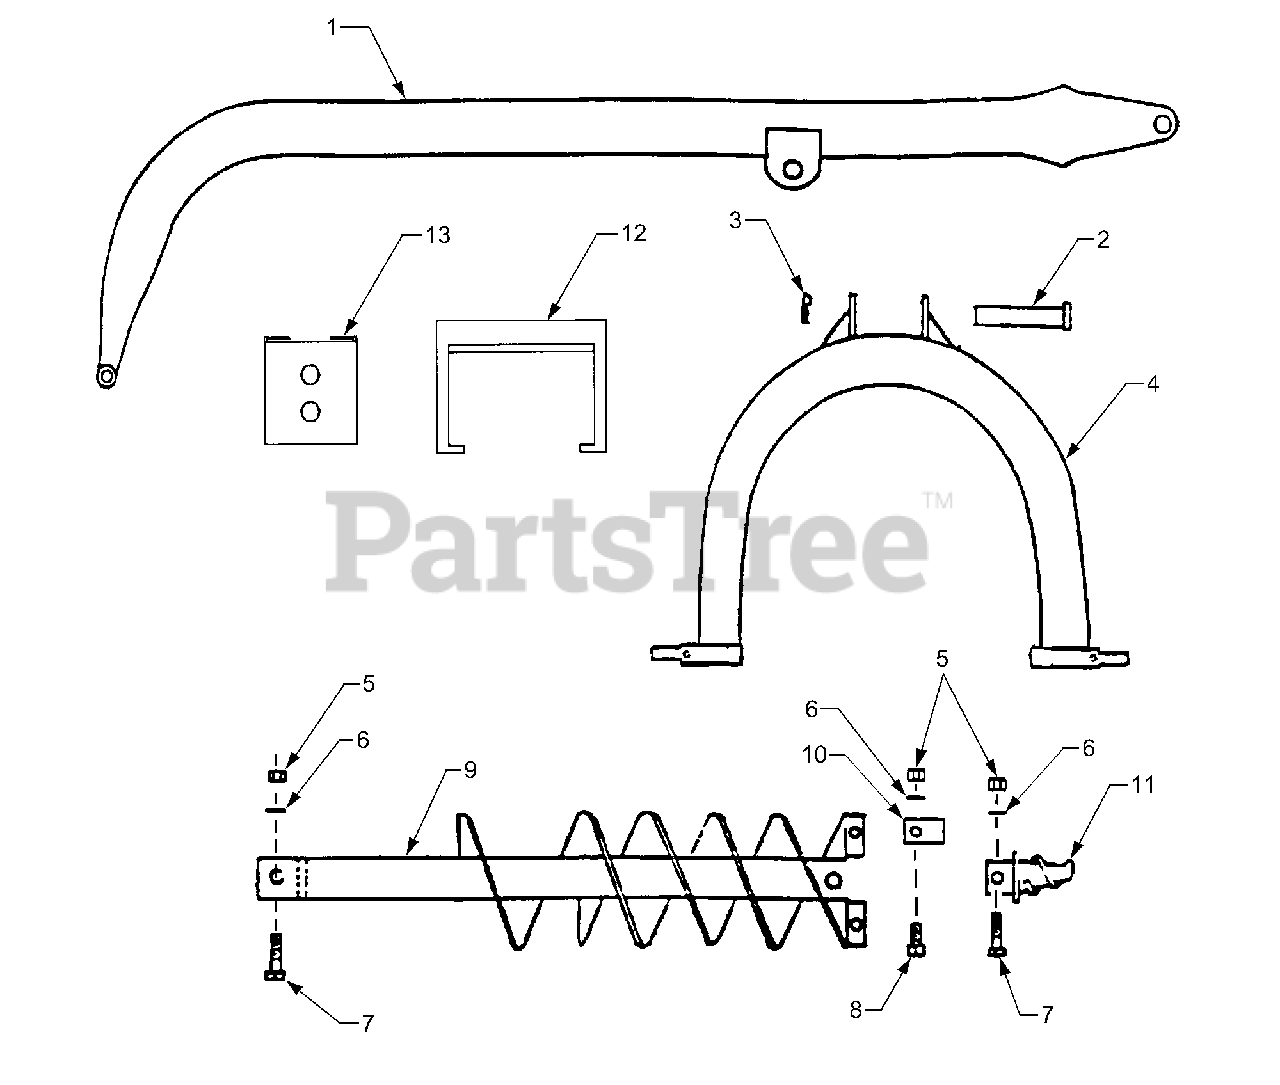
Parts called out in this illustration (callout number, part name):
1	Boom Assembly
2	Pin, 1" x 6"
3	Hairpin Cotter
5	Hex Nut, M12
6	Lock Washer, M12
7	Hex Cap Screw, M12 x 80
8	Hex Cap Screw, M12 x 30
9	9" Auger - Double Flighted
10	Cutting Teeth
11	Auger Point
12	Gearbox Guard
13	Auger Guard
